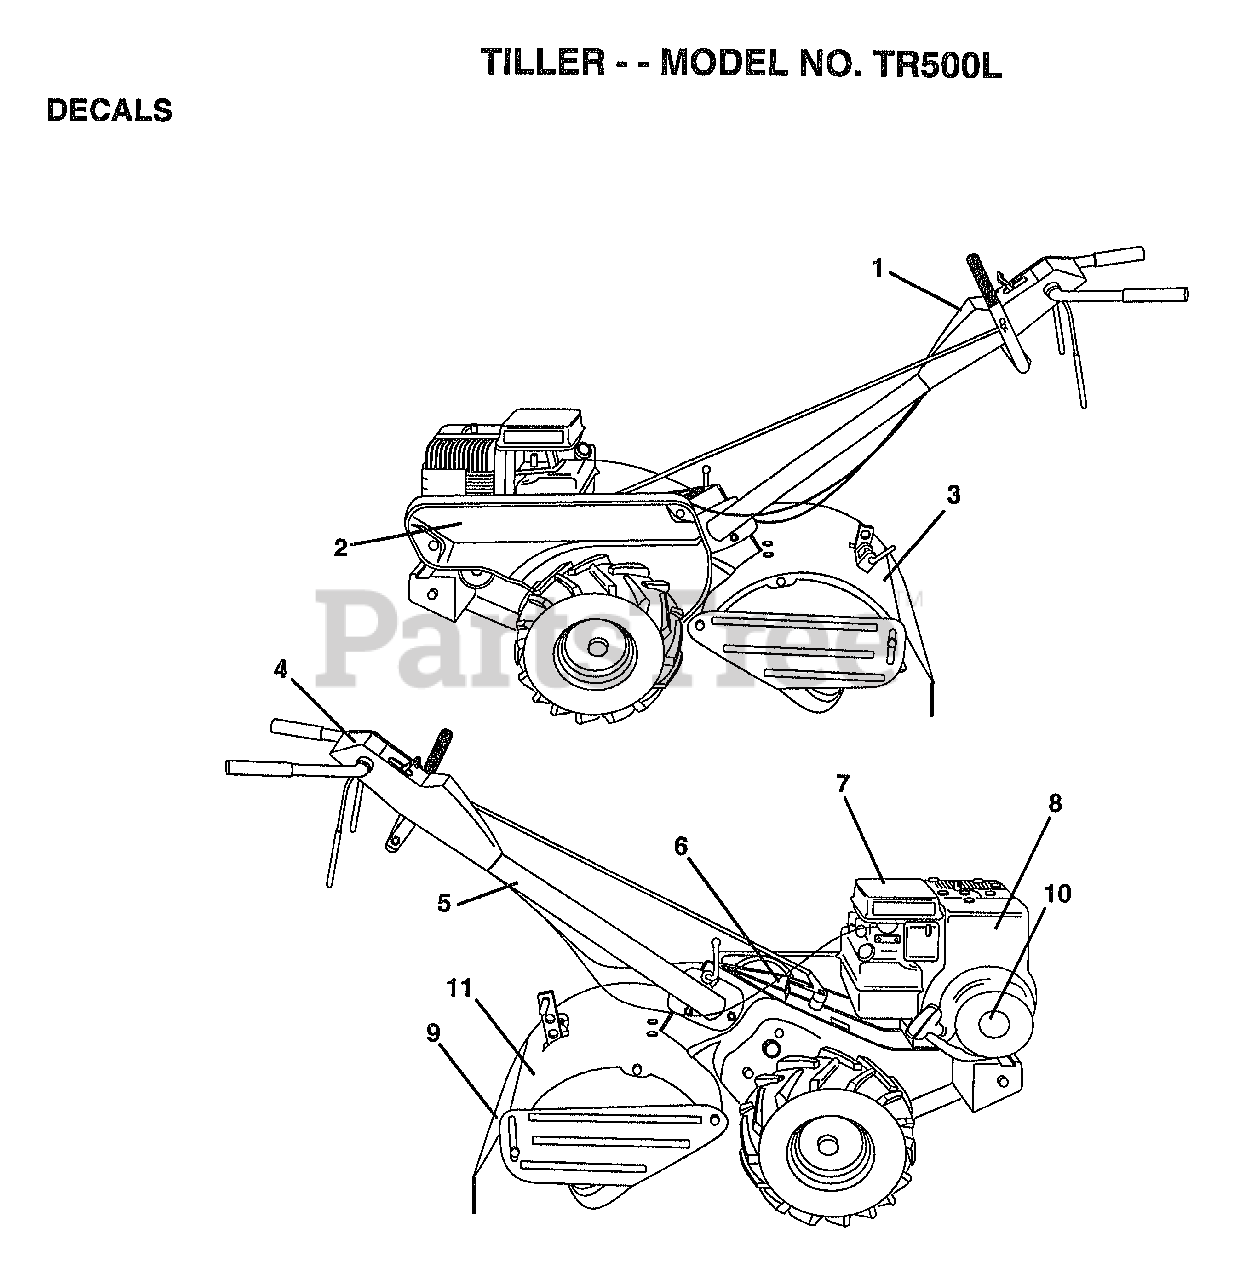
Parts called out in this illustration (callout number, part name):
1	DECAL.PNL.CONTROL
3	DECAL.SHLD.TINE
4	DECAL.INSTRUCTION
5	DECAL TI
6	DECAL CRT
8	DECAL, BRIGGS & STRATTON
9	DECAL TI
11	DECAL.TINE.SHIELD
